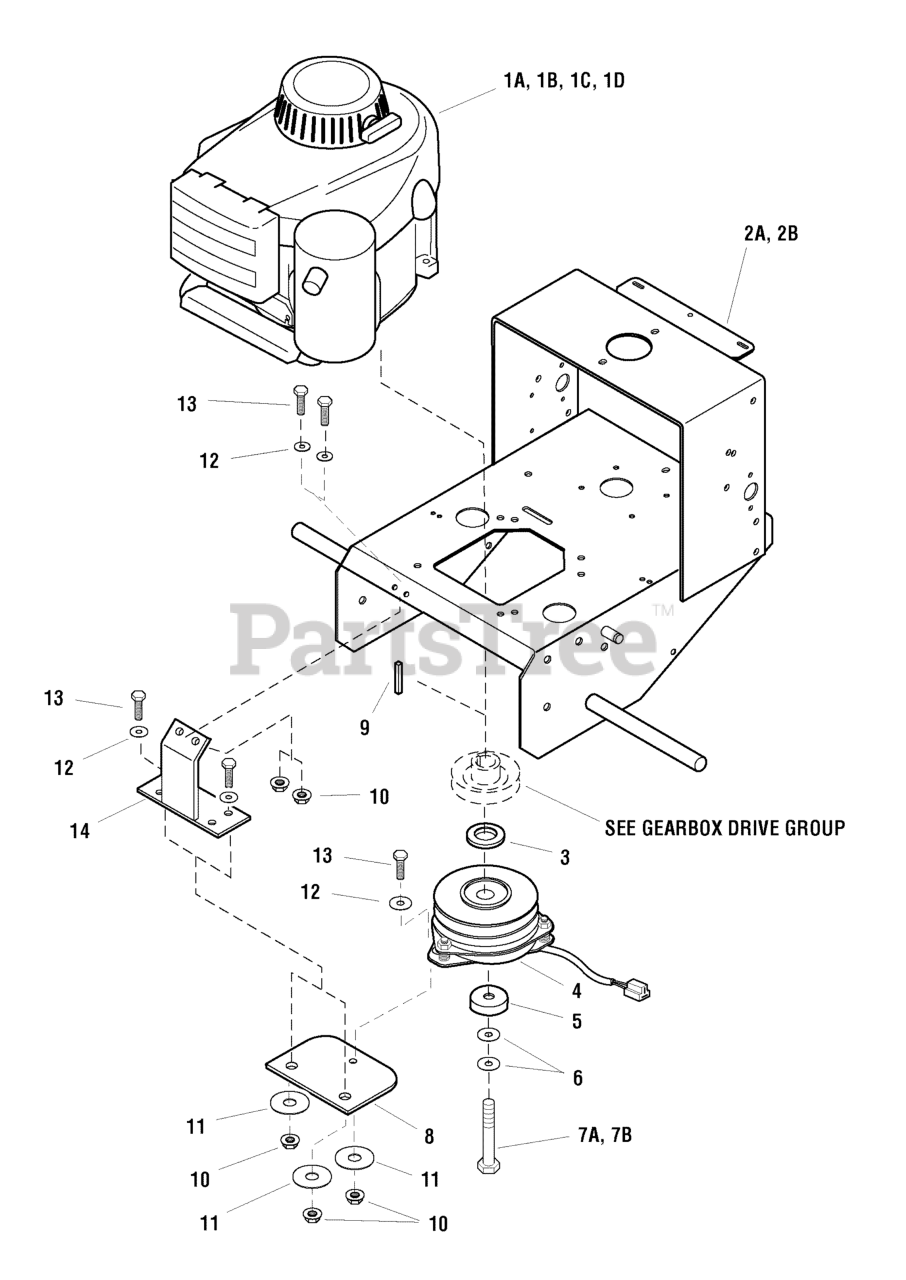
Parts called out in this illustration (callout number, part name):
2A	ENGINE DECK
2B	ENGINE DECK
3	SHIM, 1.0 X 1.5 X 0.125
4	CLUTCH, Electric
5	SPACER, .45 x 1.62 x .37
6	WASHER, 7/16" SAE
7A	CRANKSHAFT BOLT, 10 mm x 70 mm
7B	CRANKSHAFT BOLT, 7/16 x 2-1/2
8	CLUTCH ANCHOR PAD
9	KEY, 1/4 SQ. X 1
10	NUT, 5/16-18 Hex Nylon Flange
11	WASHER, Clutch Anchor
12	WASHER, 5/16" SAE
13	BOLT, 5/16-18 X 1 GD5 YZ
14	ANCHOR, Clutch
